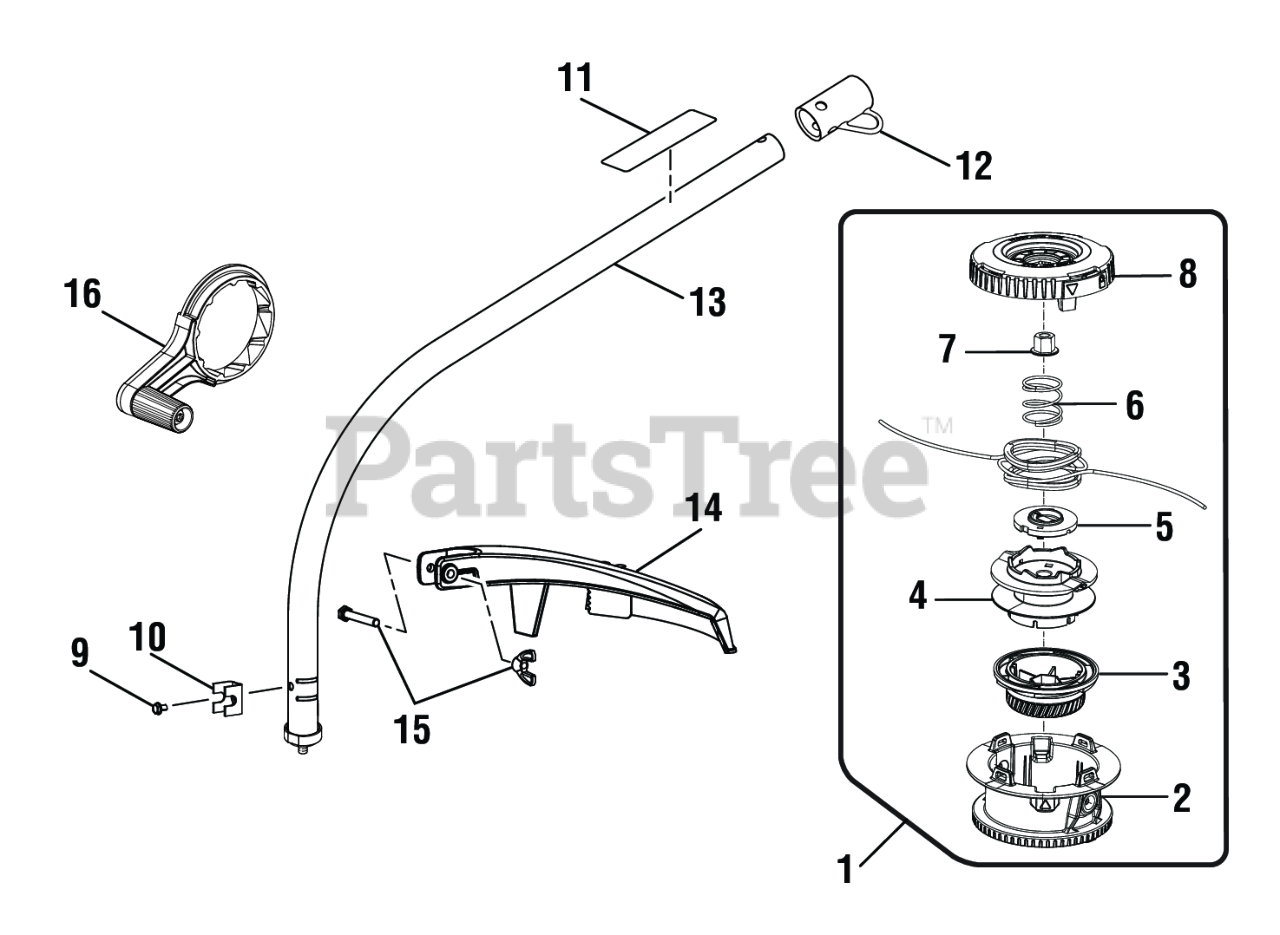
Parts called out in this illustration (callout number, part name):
1	Trimmer Head Assembly (.095) (Inc. Key Nos. 2-8)
2	Bump Head
3	Bump Knob (Green)
4	Spool Assembly
5	String Guide
6	Compression Spring
7	Flange Nut (M8)
8	Locking Assembly
9	Screw (#10-32 x 3/8 in., Hex Washer Hd. S.T.)
11	Warning Icon Label
12	Storage Hanger Cap
13	Curved Shaft Assembly (Inc. Key Nos. 9-12)
14	Grass Deflector Assembly
15	Fastener Parts Kit
16	Crank Handle
